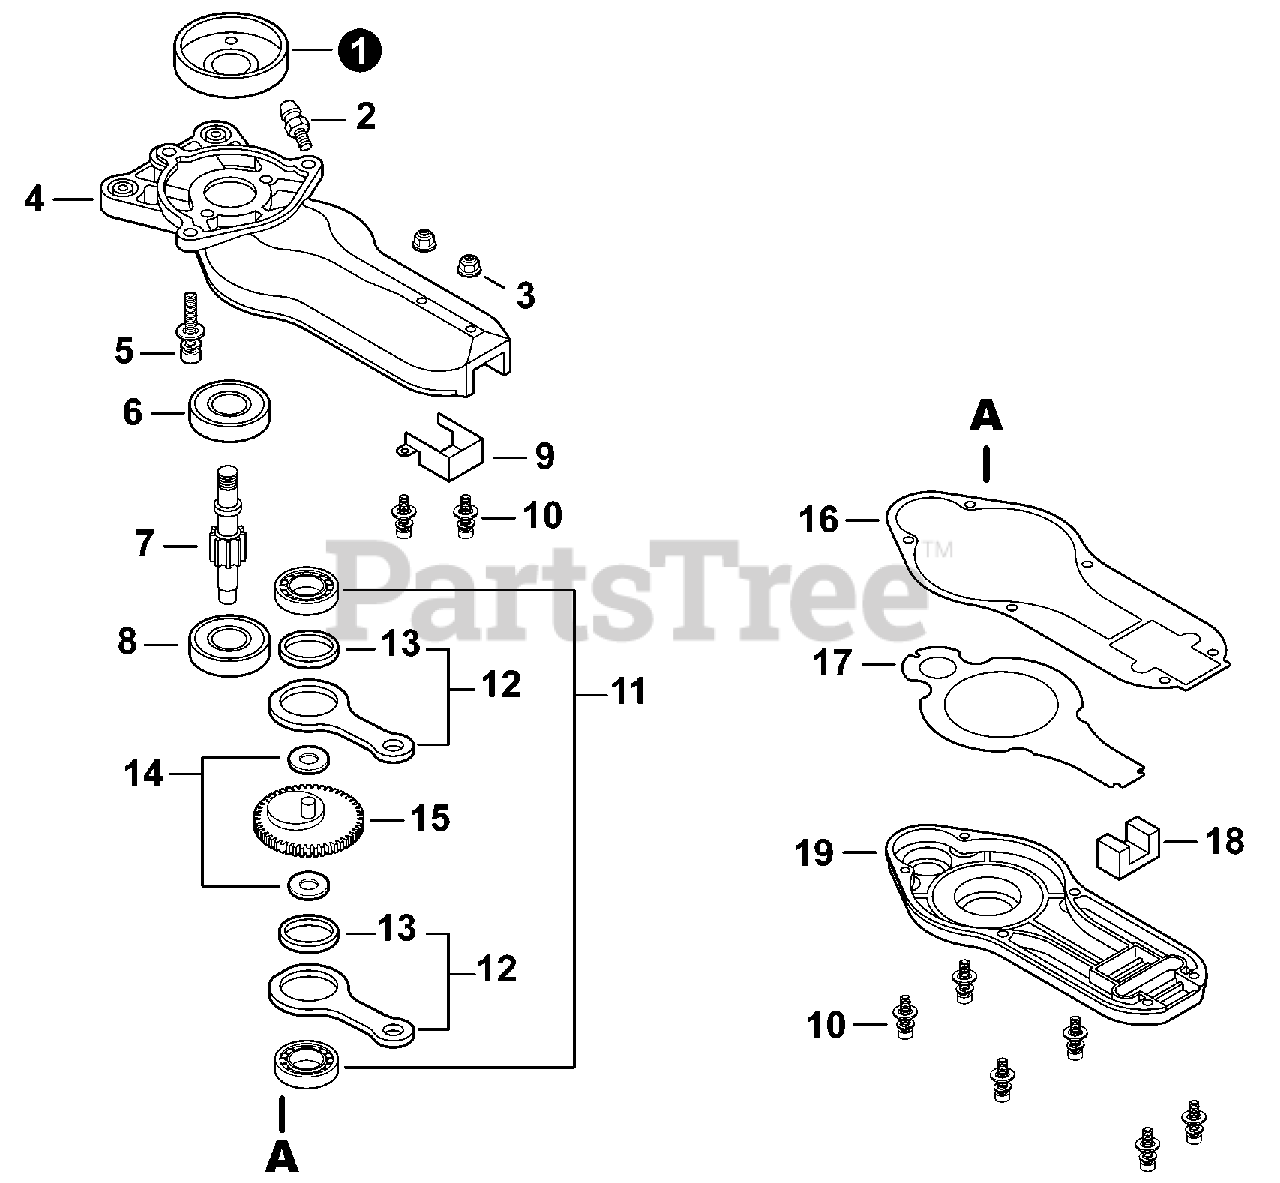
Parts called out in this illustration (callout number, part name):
1	DRUM, CLUTCH
2	FITTING, GREASE
3	NUT, FLANGE M6
4	CASE, GEAR - UPPER
5	BOLT 6×18
6	BEARING, BALL 6200
7	GEAR, SPUR
8	BEARING, BALL 608ZZ
9	GUIDE, BLADE
10	BOLT 4×16
11	BEARING, BALL 6200
12	ROD, CONNECTING
13	BEARING, NEEDLE 30
14	WASHER, THRUST 10
15	GEAR, SPUR
16	GASKET, GEAR CASE
17	PLATE, GEAR CASE
19	COVER, GEAR CASE
